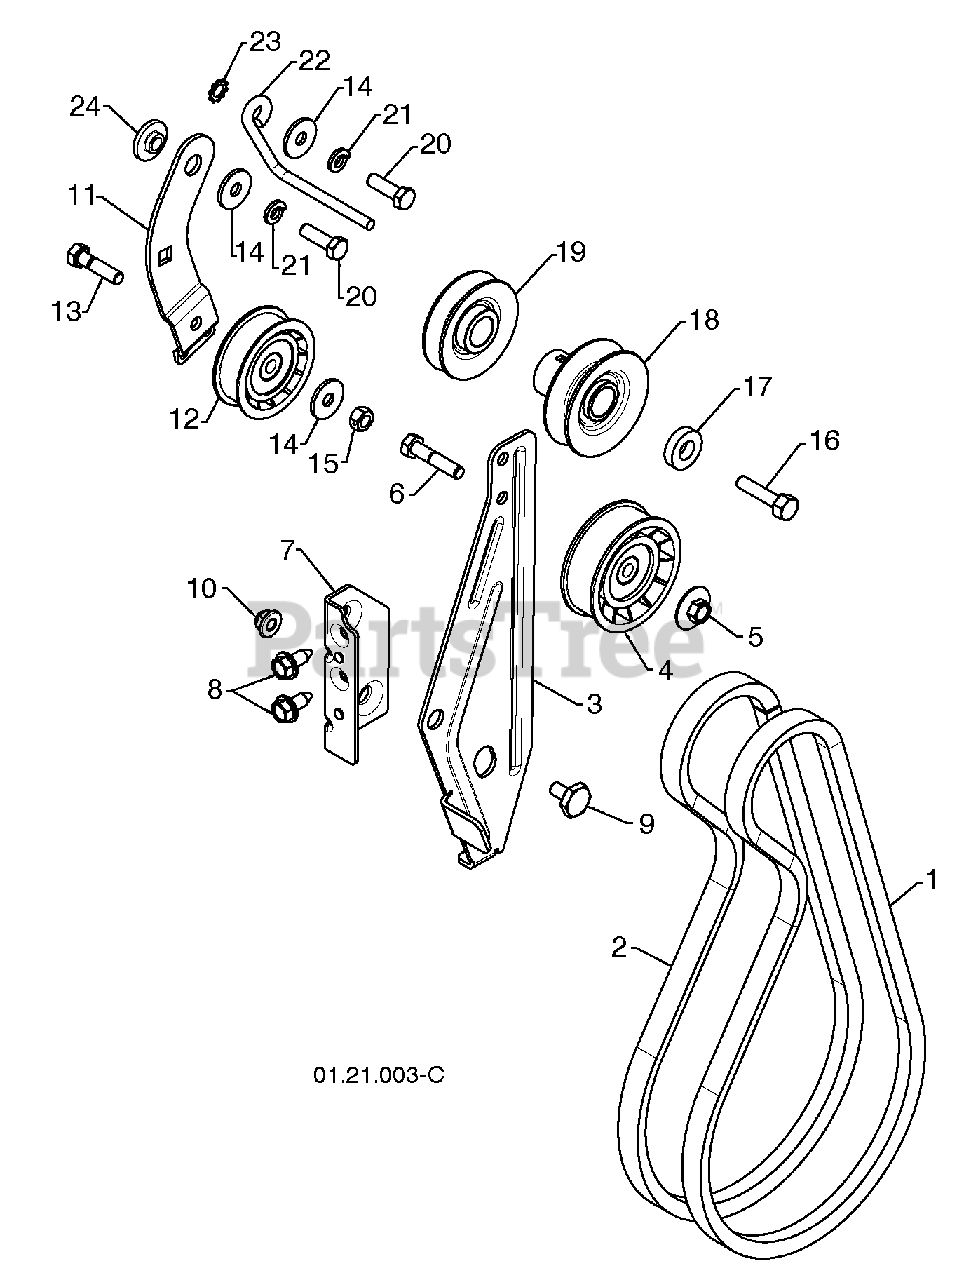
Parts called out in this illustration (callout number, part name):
1	IMPELLER BELT
2	TRACTION BELT
3	IDLER ARM BRACKET
4	IDLER PULLEY
5	NUT 5/16-18
6	SCREW 5/16-18 X 1.50
7	IDLER BRACKET
8	SCREW 5/16-18 X .75
9	SHOULDER BOLT 5/16-18 X .500
10	NUT 5/16-18 NYLOCK
11	TRACTION IDLER ARM
12	TRACTION PULLEY
13	SCREW 5/16-18 X 1.00
15	NUT 5/16-18
16	SCREW 3/8-24 X 1.375
18	PULLEY ENG IMPELLER
19	PULLEY ENG TRACTION
20	SCREW 5/16-18 X 1.00
21	LOCKWASHER 5/16
22	BELT GUIDE
23	LOCKWASHER 5/16
24	IDLER BUSHING
